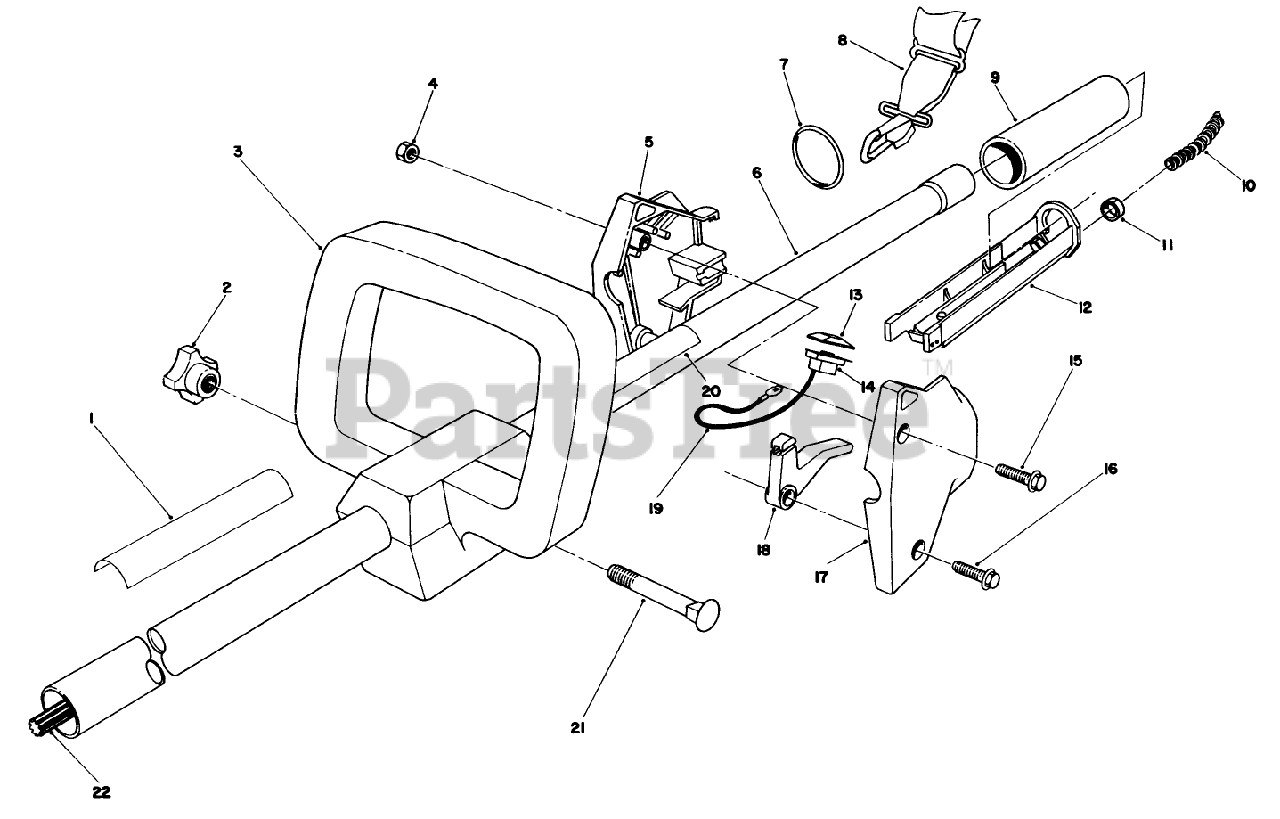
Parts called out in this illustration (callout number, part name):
4	NUT-LOCK, NI
5	THROTTLE HSG.R H
7	RING-HARNESS
9	GRIP - RUBBER
10	CABLE COVER
11	RING FITTING
12	TROUGH 1"
14	SWITCH
16	SCREW-HWH
